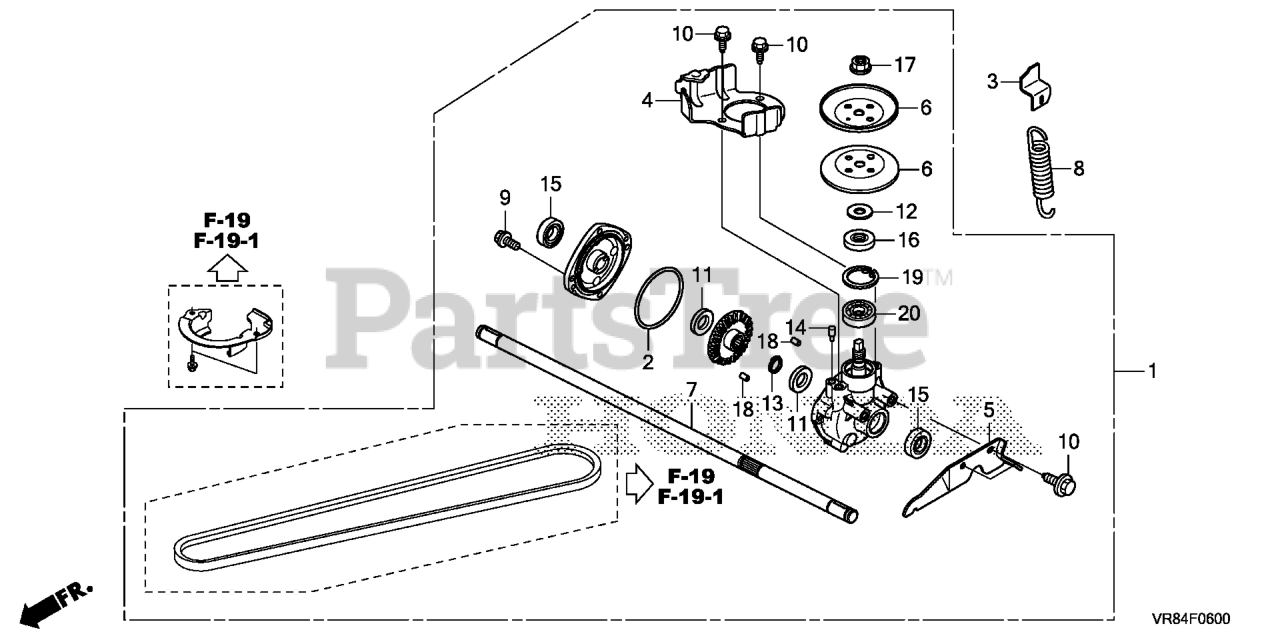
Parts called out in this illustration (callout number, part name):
1	TRANSMISSION ASSY.
2	O-RING, CASE
3	BRACKET, CLUTCH SPRING
4	GUIDE, BELT
5	STAY, TENSIONER SPRING
6	FACE, DRIVEN
7	SHAFT, FINAL
8	SPRING, WHEEL TENSION
9	BOLT, FLANGE (5X16)
10	BOLT, FLANGE (6X14)
11	WASHER, PLAIN (12.7X20X0.8)
12	WASHER (10X24)
13	CIRCLIP (OUTER) (12.7MM)
14	PLUG, SEALING
15	OIL SEAL (12.7X22.2X6.4)
16	OIL SEAL (12X28X6)
17	NUT, FLANGE (10MM)
18	PIN, DOWEL (5X8)
19	CIRCLIP (INNER) (28MM)
20	BEARING, RADIAL BALL (6001)
